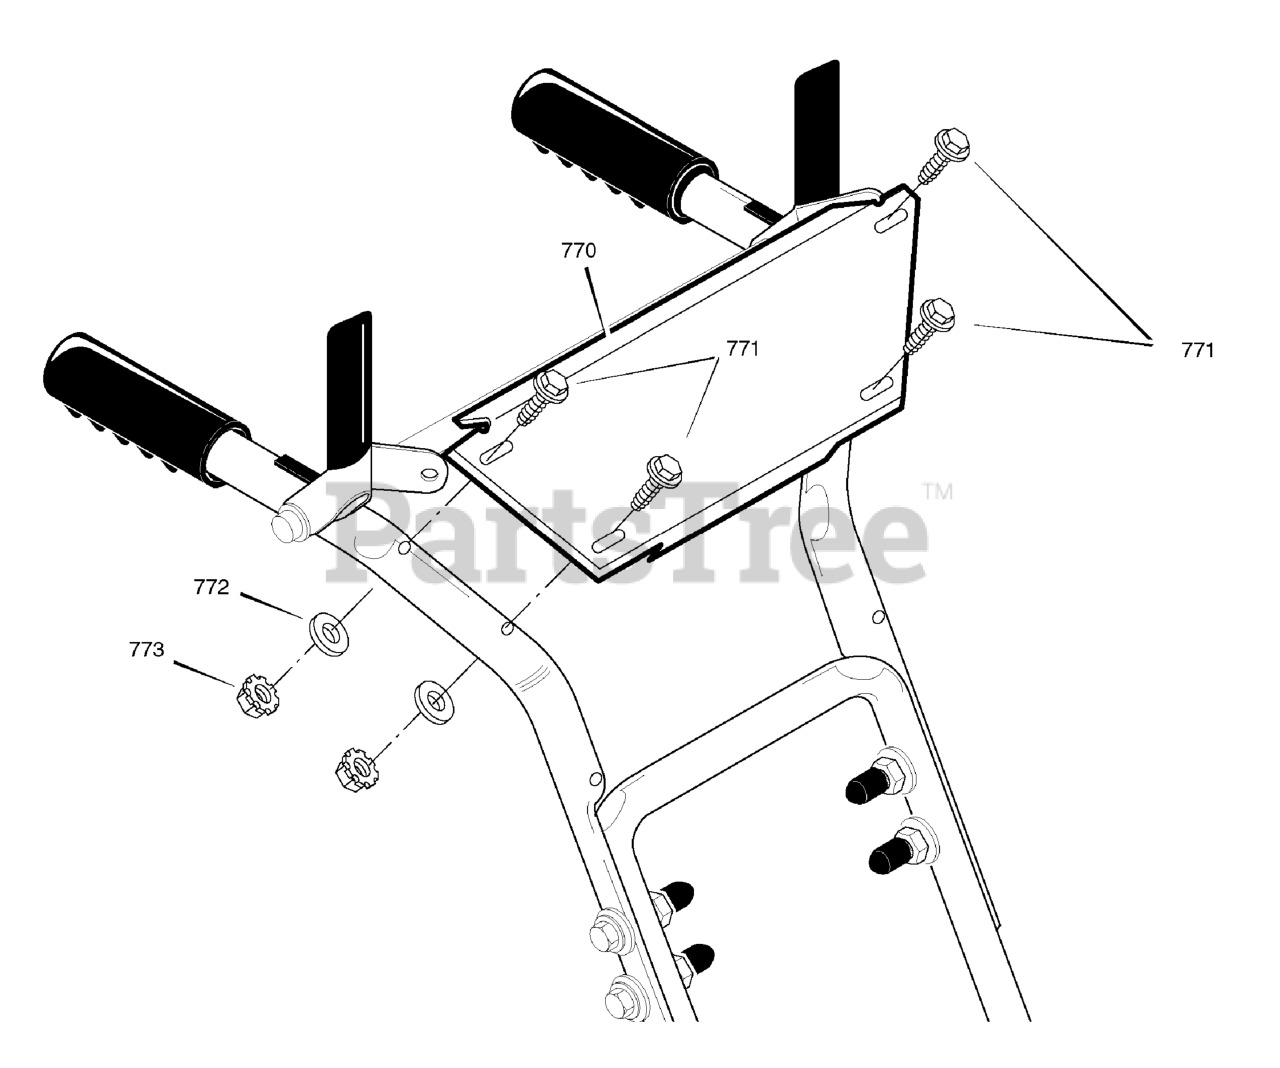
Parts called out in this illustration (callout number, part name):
771	SCREW
772	WASHER
773	NUT
